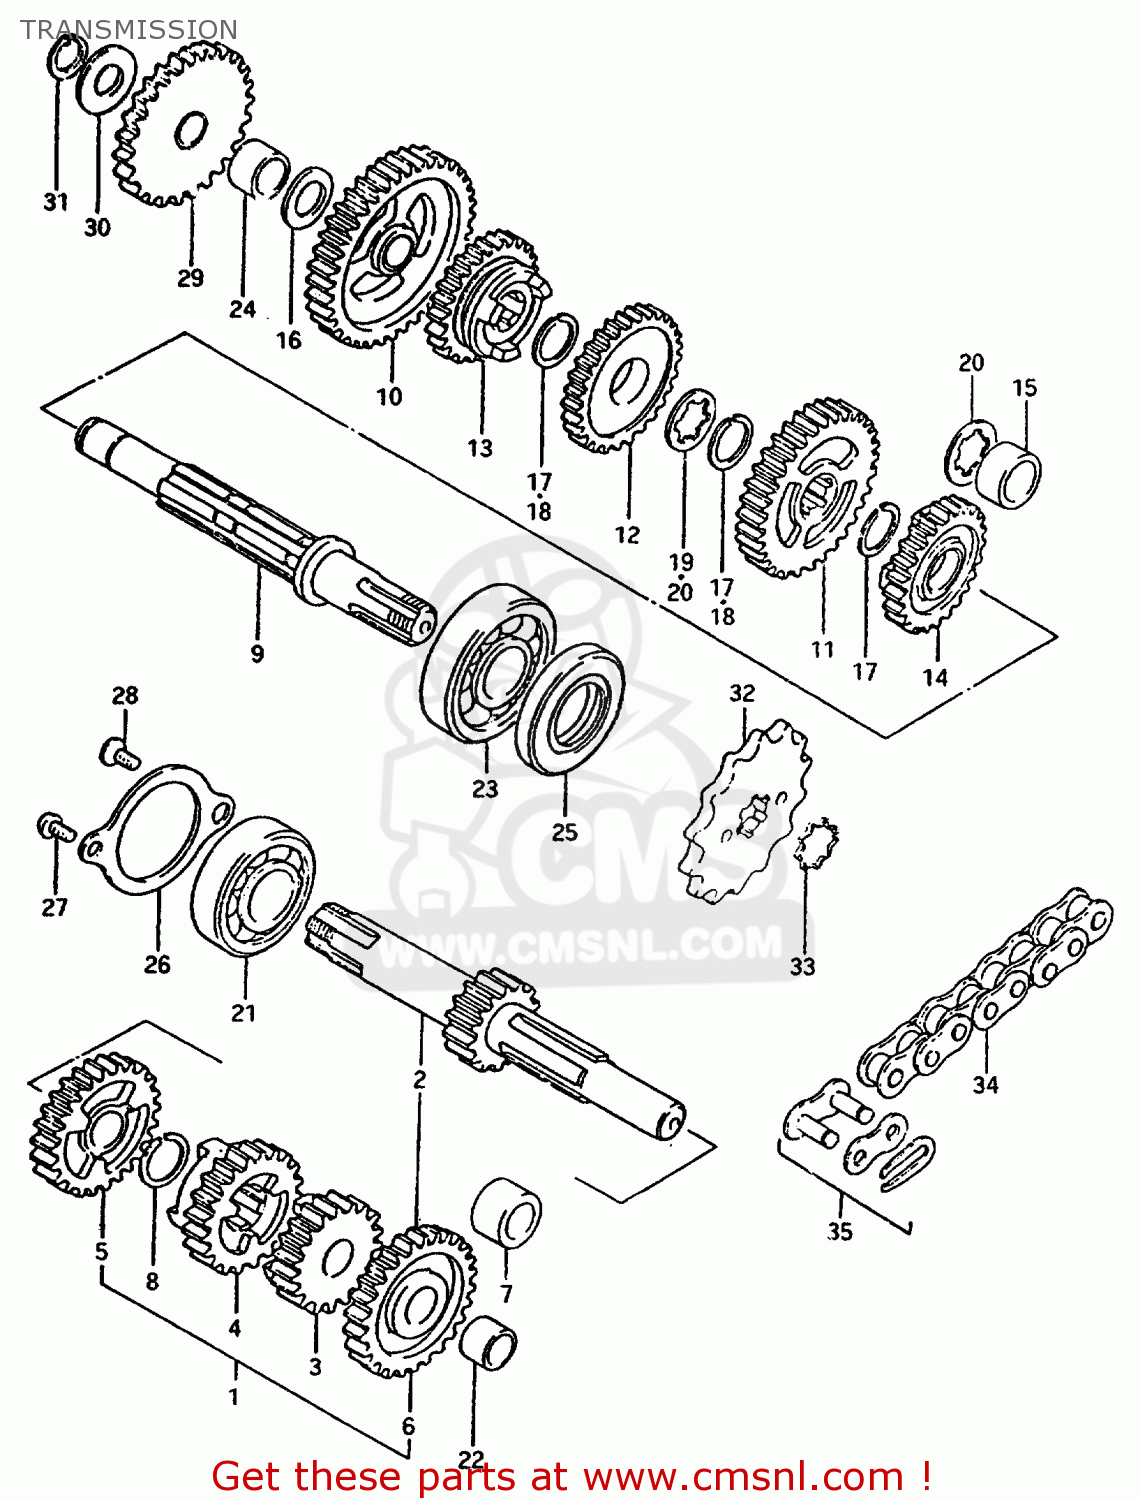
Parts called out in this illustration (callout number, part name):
1	SHAFT,COUNTER
2	SHAFT,COUNTER(NT:12)
3	GEAR,SECOND DRIVE
4	GEAR,THIRD DRIVE
5	GEAR,4TH DRIVE(NT:24)
6	GEAR,FIFTH DRIVE
7	SPACER
8	CIRCLIP
9	DRIVESHAFT
10	GEAR,FIRST DRIVEN
11	GEAR,2ND DRIVEN(NT:33)
12	GEAR,3RD DRIVEN(NT:29)
13	GEAR,FOURTH DRIVEN
14	GEAR,5TH DRIVEN(NT:24)
15	SPACER
16	WASHER(13X24X1)
17	CIRCLIP
18	CIRCLIP
19	WASHER,LOCK
20	WASHER,LOCK
21	BEARING
22	BUSH
23	Bearing
24	BUSH
25	SEAL,OIL(20X40X7)
26	RETAINER,CNTR SHAFT BEARING
27	SCREW
28	SCREW
29	GEAR,KICK STARTER IDLE
30	WASHER
31	CIRCLIP
32	SPROCKET,ENGINE(NT:12)
33	RING,ENGINE SPROCKET
34	CHAIN, DRIVE (420*114L)
35	JOINT ASSEMBLY,CHAIN
